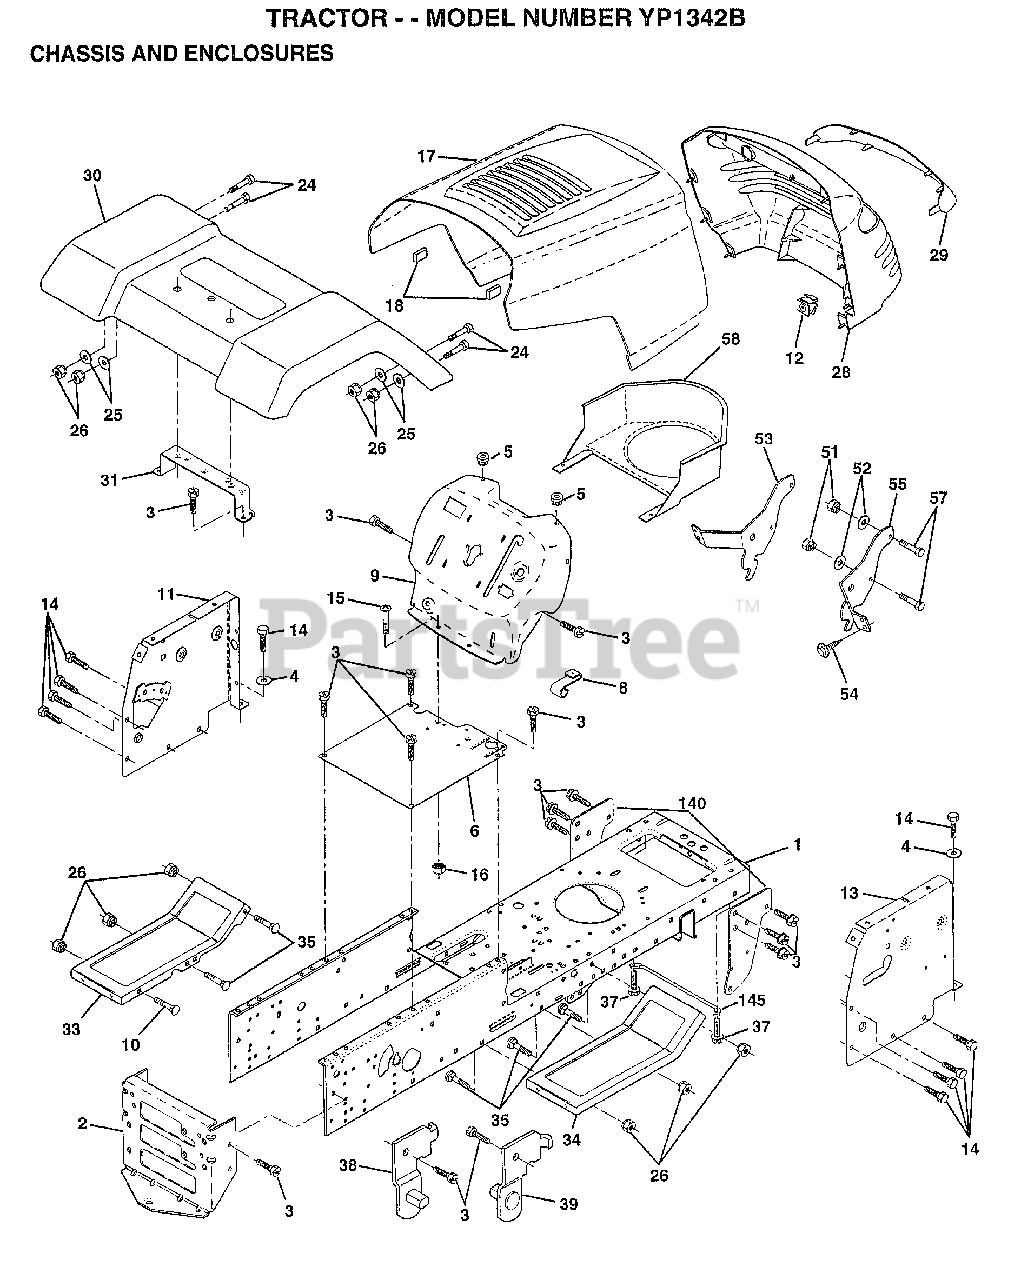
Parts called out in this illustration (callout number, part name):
1	CHASSIS ASM
3	SCREW
4	WASHER
5	BUMPER-HOOD/DASH
6	SADDLE
8	CLIP.RETAINER
9	DASH SILKSCREEN
11	"PANEL-DASH,LH"
12	CLIP.TINNERMAN
13	"PANEL-DASH,RH"
14	SCREW LT
15	SCREW
17	"HOOD W/TRIM,MS428"
24	BOLT
25	WASHER
26	NUT
28	GRILL
29	LENS.EURO.W/DECAL
30	FENDER ASM LT W/S
31	BRKT FENDER
33	FOOTREST PNT LH
34	FOOTREST.RH.LT/GT
35	BOLT
37	SCREW LT
38	BRACKET ASM LH
39	BRACKET ASM RH
51	NUT
52	WASHER
53	BRACKET.GRILLE.LH
55	BRACKET.GRILLE.RH
58	AIR DUCT
140	BRKT SUSPENSION
145	"ROD POVOT,CHASSIS"
